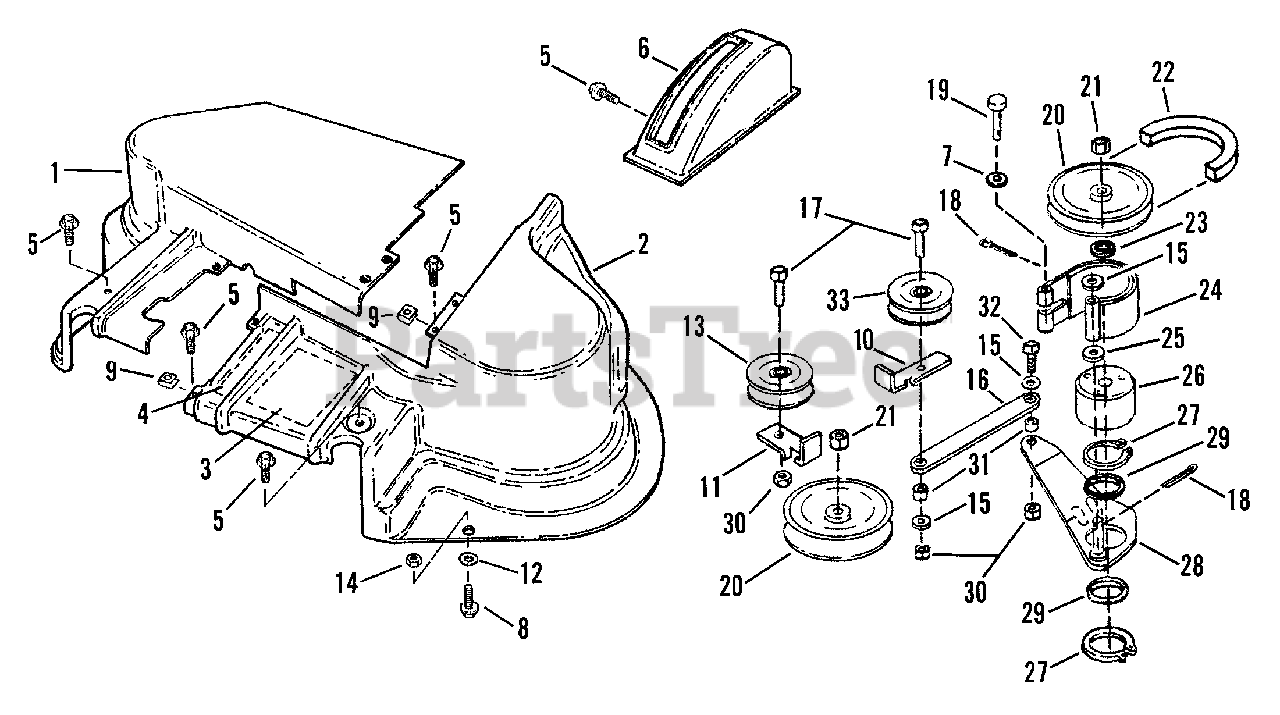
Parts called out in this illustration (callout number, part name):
1	ASSEMBLY, 42" Cover (Right Half)
2	ASSEMBLY, 42" Cover (Left Half)
3	DECAL, Brake Operation
4	DECAL, Blade (ON-OFF)
5	SCREW, 1/4-20 x 5/8" Self-Tapping
6	COVER, Lift Quadrant
7	WASHER, 1/4 Flat
8	BOLT, 3/8-16 x 3/4" Short Neck Carriage
9	NUT, 1/4-20 Tinnerman
10	RESTRICTOR
11	GUIDE, Belt
12	RETAINER, 3/8 Bolt
13	PULLEY, Idler
14	NUT, 3/8-16 Hex Lock
15	WASHER, 3/8" Flat
17	SCREW, 3/8-24 x 1-3/4" Hex Head Cap
18	PIN, 3/32 x 3/4" Cotter
19	PIN, 1/4 x 1-5/8" Clevis
20	PULLEY, 5" O.D.
21	NUT, 3/4-16 Hex Jam Lock
22	BELT, AA105
23	WASHER, 3/4 Flat
24	ASSEMBLY, Brake Band
25	SPACER
26	BRAKE DRUM
27	RING, 2" External Retaining
28	ASSEMBLY, Brake Arm
29	WASHER, 2" I.D.
30	NUT, 3/8-24 Hex Lock
31	SPACER
32	SCREW, 3/8-24 x 3/4" Hex Head Cap
33	PULLEY, Idler
